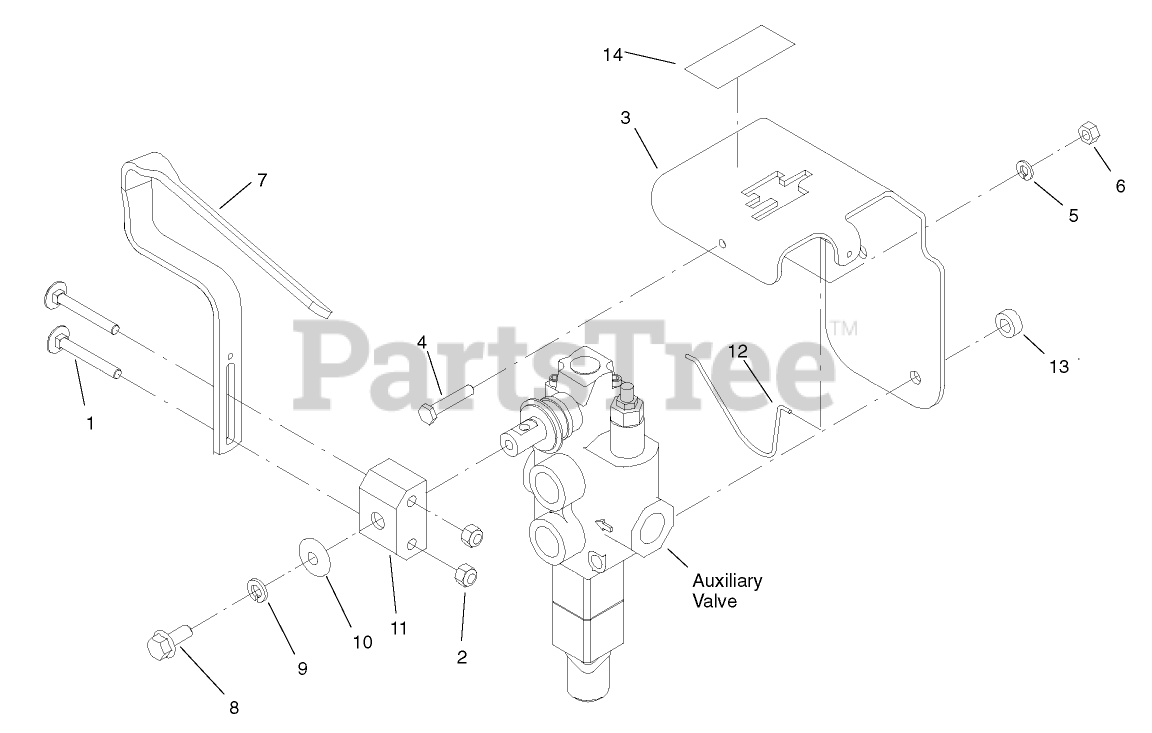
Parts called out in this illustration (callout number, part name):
1	SCREW-CARR
2	NUT-LOCK, NI
3	BRACKET
4	SCREW-HH
5	WASHER-LOCK
6	NUT-HEX
7	GRIP-CONTROL
8	SCREW-HHF
9	WASHER-LOCK
10	CAP-MOUNT
11	MOUNT-LEVER
12	SPRING-TORSION
13	SPACER
14	DECAL-POWER, AUXILIARY
